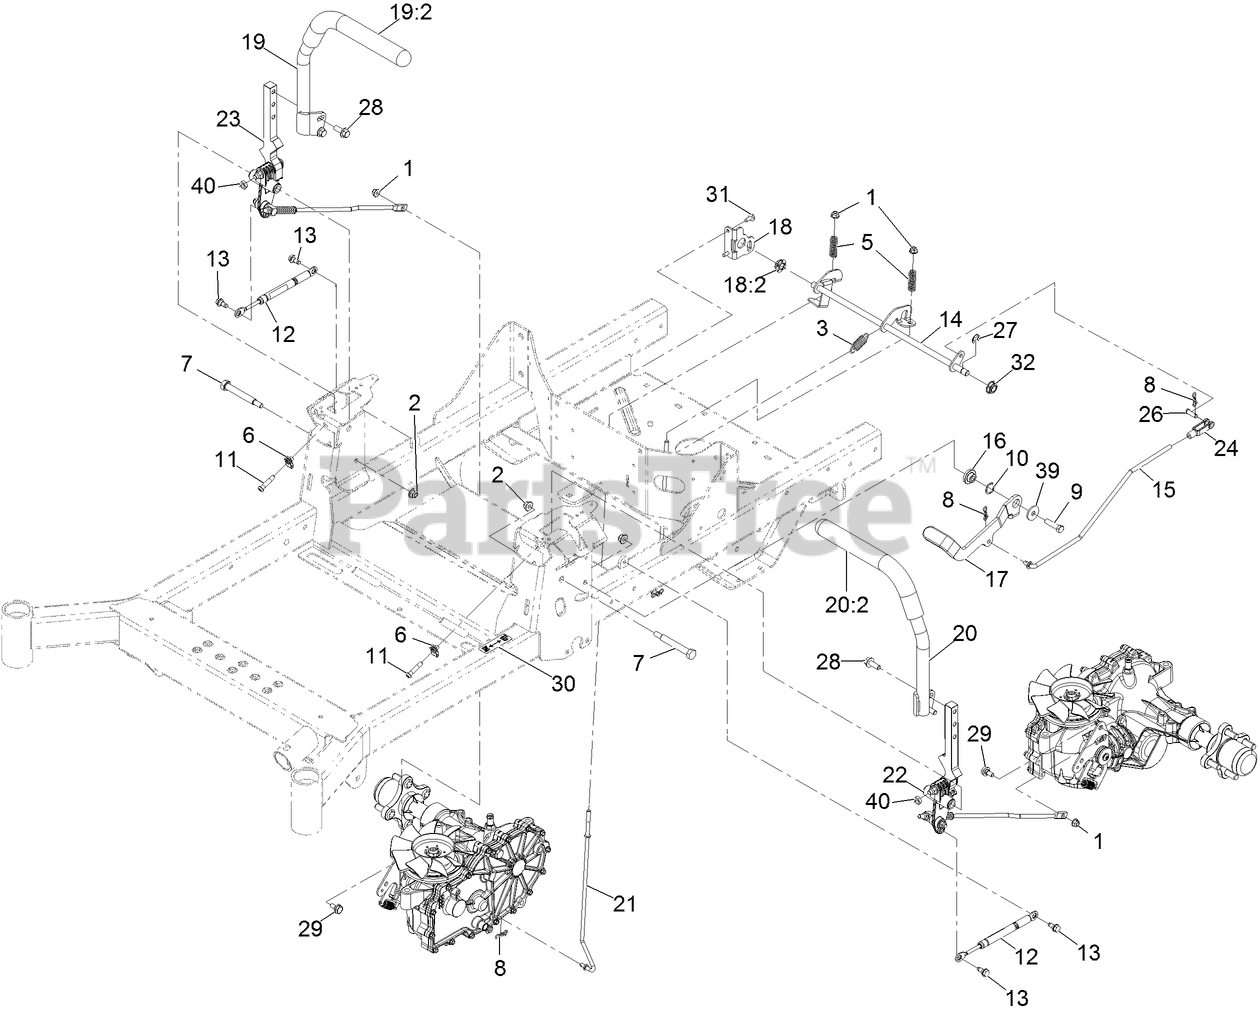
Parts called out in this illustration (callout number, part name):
1	NUT-HF, NI
2	NUT-HF, NI
3	SPRING-EXTENSION
5	SPRING-COMPRESSION
7	BOLT-PIVOT
8	PIN-COTTER, LOCKING
9	SCREW-HH
10	WASHER-WAVE
11	SCREW-HSBH
12	DAMPER
13	SCREW-SHOULDER
14	SHAFT-BRAKE
15	LINKAGE-BRAKE, UPPER
16	PIVOT-FLANGE
17	LEVER-BRAKE (WITH GRIP)
18	BRACKET-BRAKE
18:2	BEARING-SPHERICAL
19	RH CONTROL HANDLE ASM
20	LH CONTROL HANDLE ASM
21	LINKAGE-BRAKE, LOWER
22	LH MOTION CONTROL ASM
23	RH MOTION CONTROL ASM
24	YOKE-ADJUSTABLE
26	PIN-CLEVIS
27	RING-RETAINING, EXTERNAL
28	SCREW-HHF
29	BOLT-SHOULDER
30	DECAL-BRAKE, PARKING
31	SCREW-TORX
32	BEARING-SPHERICAL
39	WASHER
40	NUT-JAM
